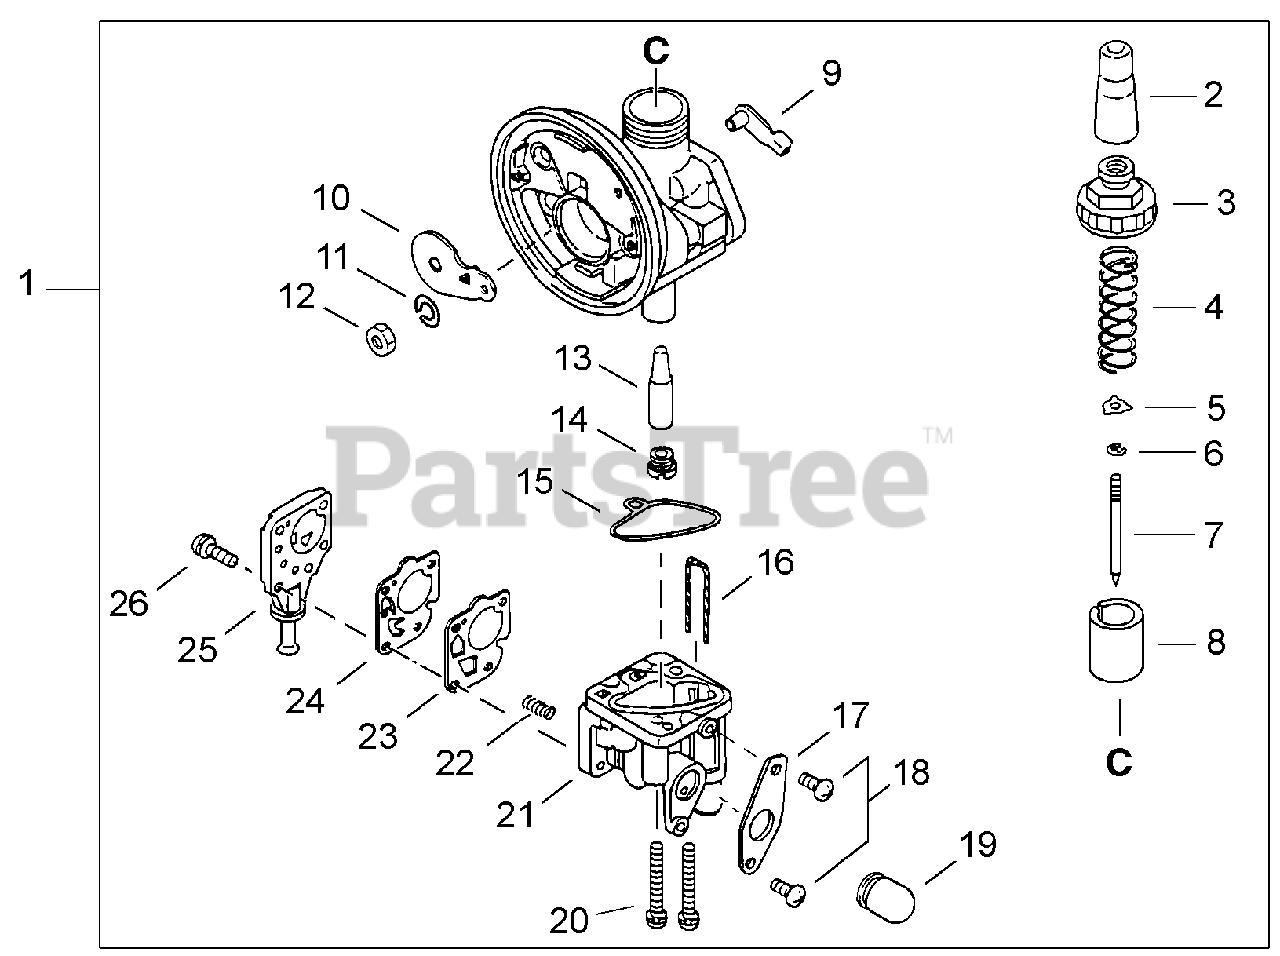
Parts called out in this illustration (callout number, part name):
1	CARBURETOR K13PR-6E
2	CAP, DUST
3	COVER - TOP
4	SPRING, THROTTLE
6	RING, RETAINING
7	NEEDLE, JET
8	VALVE, THROTTLE
9	LEVER, CHOKE
10	PLATE, CHOKE
11	LOCKWASHER - 6
13	NEEDLE, JET
14	JET, MAIN - 64
15	GASKET, CHAMBER
16	WIRE, DRAIN
18	SCREW - 4X8
20	SCREW - 4X30
23	GASKET, METERING
24	DIAPHRAGM, PUMP
25	COVER, PUMP
26	SCREW - 3X10
